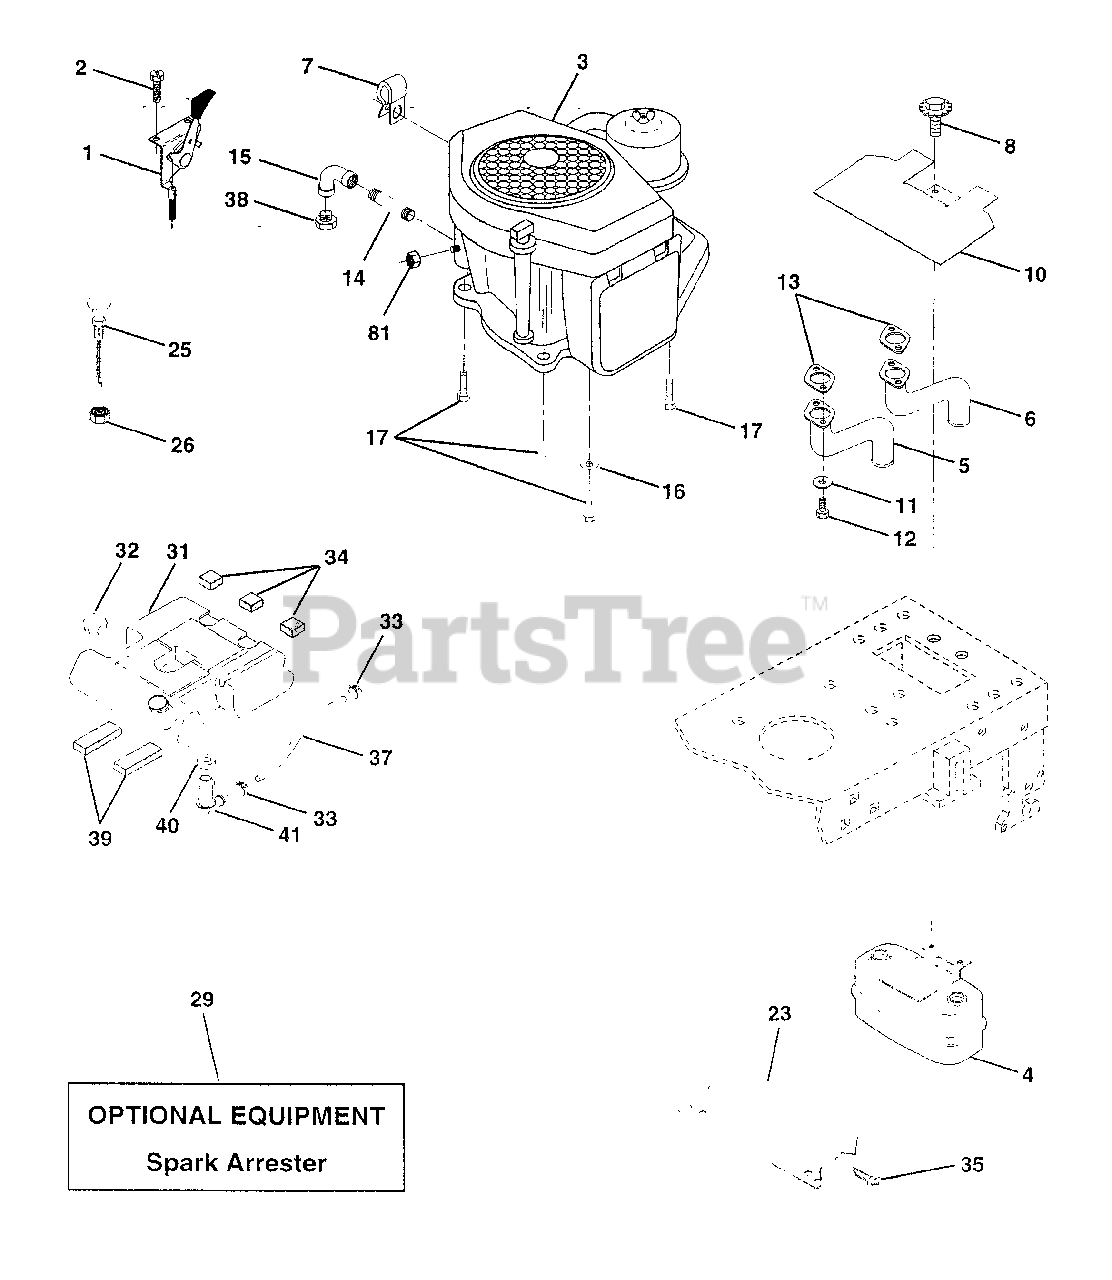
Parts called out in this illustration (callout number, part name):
1	Control Throt Flg 180 LH
2	Screw Hex Thd Cut 1/4-20x5/8 T
4	Muffler Asm Twin Lo-Tone
5	Pipe Exhaust CV18/20 LH
6	Pipe Exhaust CV18/20 RH
7	Clip, Fuel Line
8	Bolt 5/16-18unc x 3/4 W/Sems
10	Shield Heat Muffler CV18/20
13	Muffler Gasket
14	Nipple Pipe 3/8 Npt X 4-1/2"
15	Elbow Std 90 Degree 3/8-18 Npt
16	Washer Lock Ext Tooth 3/8
17	Screw Thdrol 3/8-16 x 1-1/2
23	Shield Browning
25	Choke Control 37"
26	Nut, Keps 3/8-24 Unf
29	Kit Spark Arrestor (Flat Scrn)
31	Tank Fuel 3 50 STL w/o Sensor
32	Cap Asm Fuel Top N/Lany Vented
33	Clamp Hose Blk
34	Pad, Spacer
35	Screw Thdrol 5/16-18 x 3/4
37	Line Fuel 7.5
38	Plug Oil Drain
39	Pad, Idler
40	Bushing
41	Stem Tank Fuel
81	Nut Flange 1/4-20 Starter Nut
90	Guard Debris 97
91	Bolt, Blk. Fin Hex 1/4-20 unc x 1/2
92	washer, 9/32 x 5/8 x 16 Ga.
93	Nut, Lock 1/4 Lge Flg. Gr.5 Zinc
